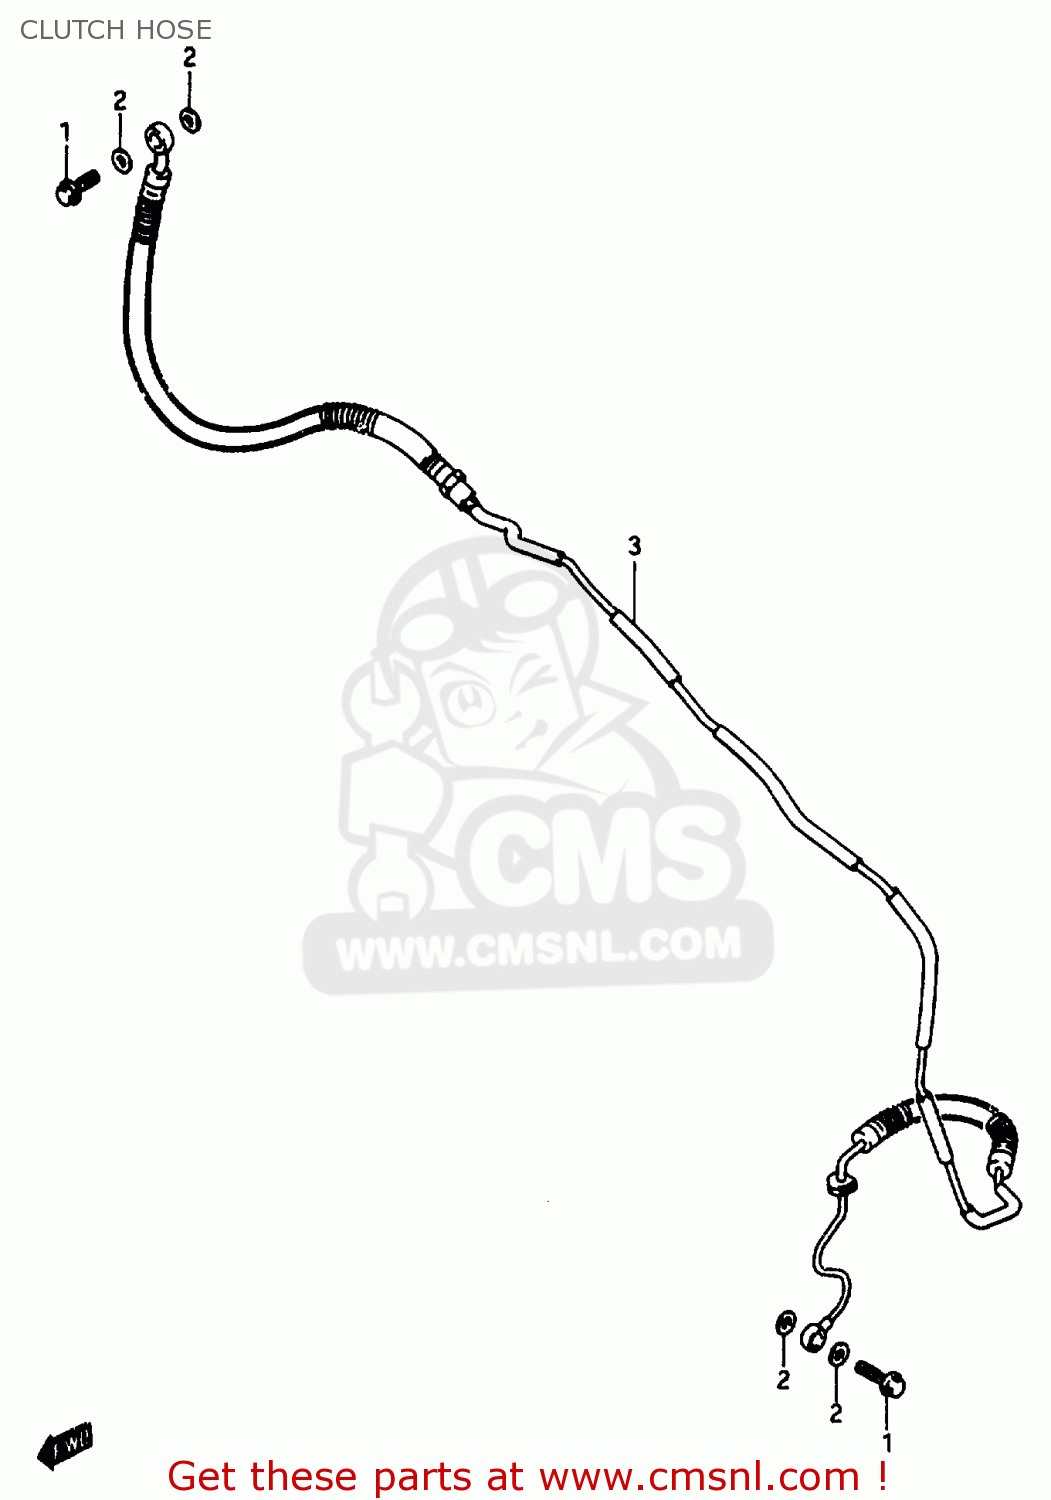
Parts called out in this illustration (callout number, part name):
1	BOLT UNION
2	WASHER(10X15X1.5)
3	HOSE, CLUTCH
